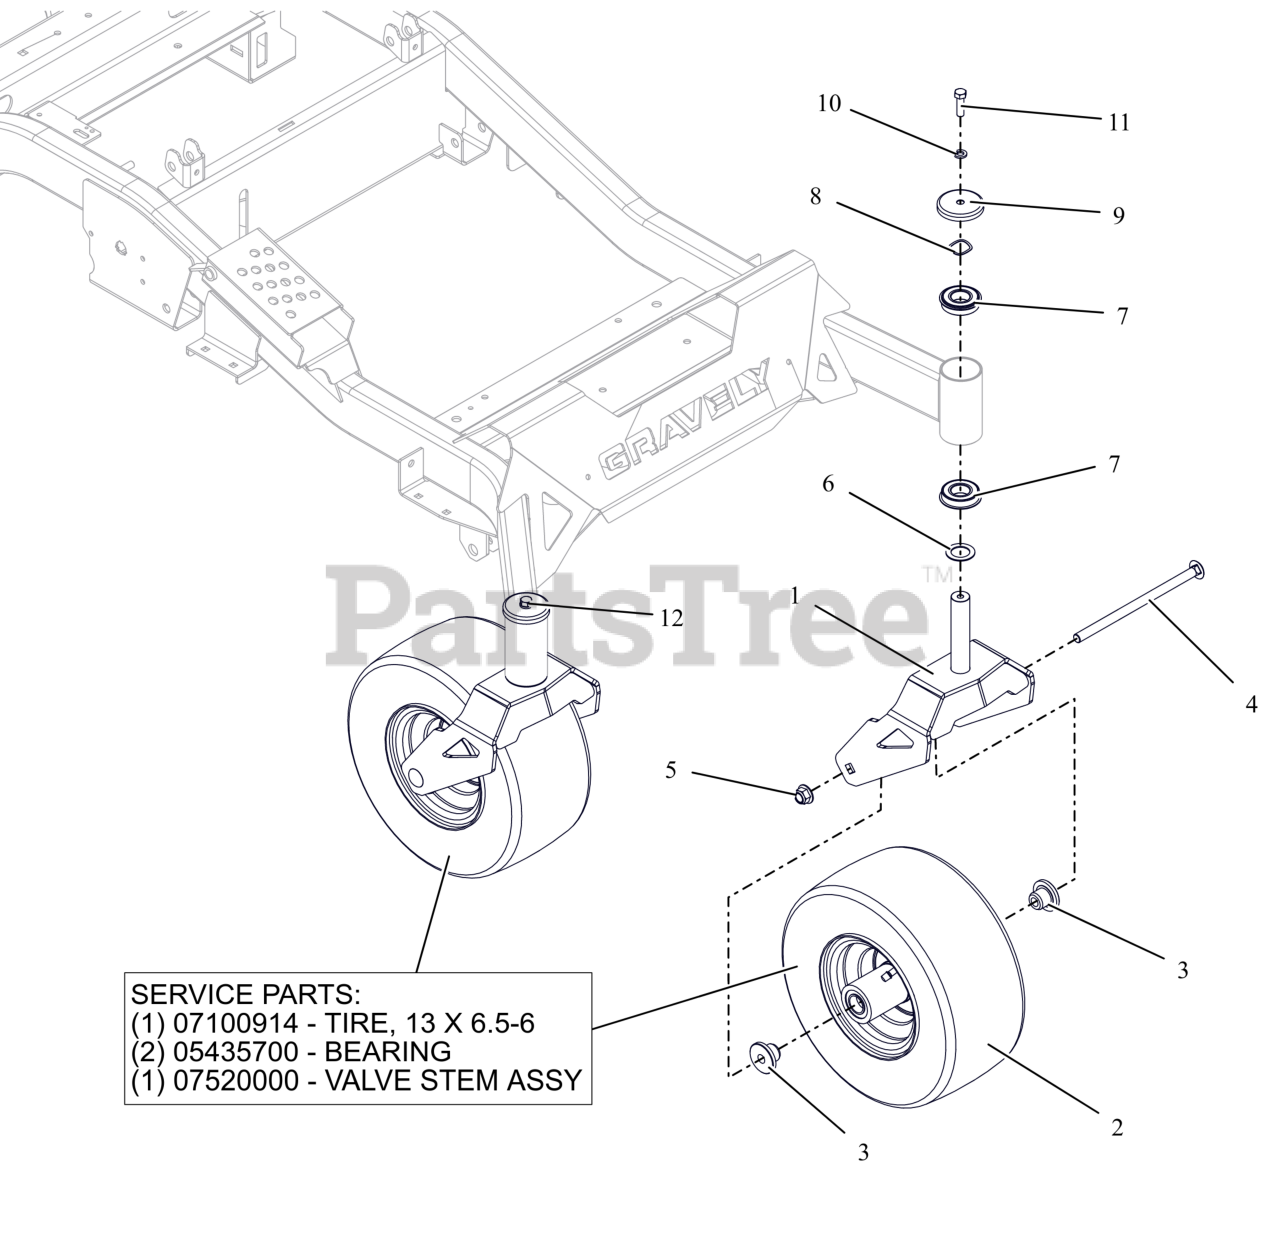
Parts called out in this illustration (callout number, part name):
1	WLDMT- HD CASTER FORK
2	ASM-TIRE/WHEEL 13X6.50-6
2	TIRE, 13X6.50-6 SMOOTH
2	BRG, 25MM ID X 52MM OD X 15MM
2	VALVE STEM ASS'Y
2	TIRE TUBE 13X6.5-6
3	SPACER, FRONT WHEEL
4	BLT-RHSN .50-13X9.00 G5 ZCC NS
5	NUT,NYL-FLG .50-13 GF ZCC
6	WSHR-HRD-THRS 1.007X1.542X.062
7	BEARING, BALL -2.000 OD X 1.000 ID X .5625 W/RING
8	WSHR-WAVE 1.0X1.25X.028 .145FH
9	SHIELD- AXLE BEARING
10	WSHR-LK-REG .375X.094 ZB500
11	BLT- HEX .38-16X1.25 G5 ZB500
12	WSHR-LK-REG .375X.094 ZB500
